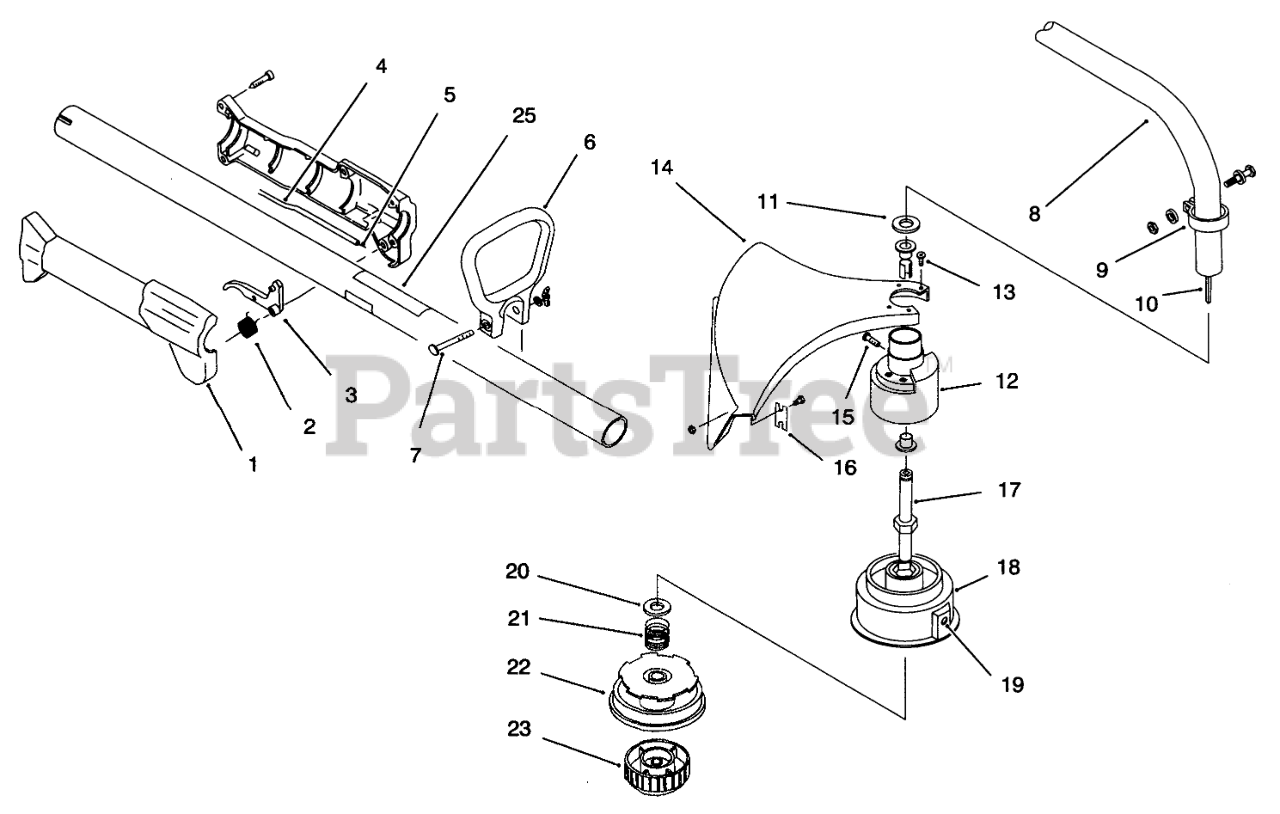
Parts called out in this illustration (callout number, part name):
1	Throttle Housing & Trigger Asm.
2	THROTTLE TRIGGER SPRING
3	TRIGGER - THROTTLE
4	HOUSING-CABLE
5	THROTTLE CABLE WIRE
6	D-HANDLE
7	HARDWARE - D-HANDLE
8	DRIVE SHAFT HSG ASM
9	CLAMP ASM - UPPER
10	Drive Shaft
12	BUSHING HSG ASM
13	GUARD MTG SCREW ASM
14	Guard and Blade Asm. (Incl. Ref. #16)
15	ANTI-ROTATION SCREW
16	BLADE ASM
17	Shaft-Spool
18	OUTER SPOOL EYELET ASM
19	EYELET
20	RETAINER ( 10 PACK)
21	SPRING
22	REEL - INNER
23	Assy.-Bump Head
25	Decal-Safety Symbol
